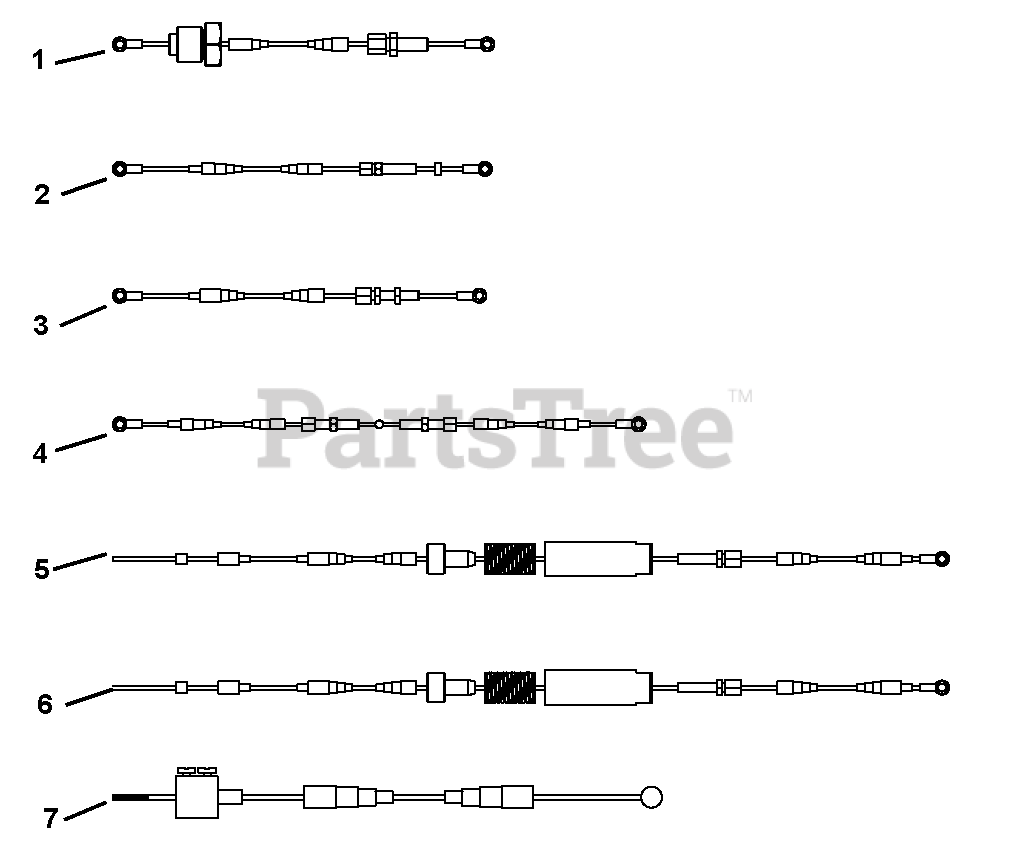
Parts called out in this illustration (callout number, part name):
1	Cable, Swivelling Handlebar
2	Cable, Steering
3	Cable, Shift
4	Cable, Driving
5	Cable, Handbrake Right
6	Cable, Handbrake Left
7	Cable, Gas
